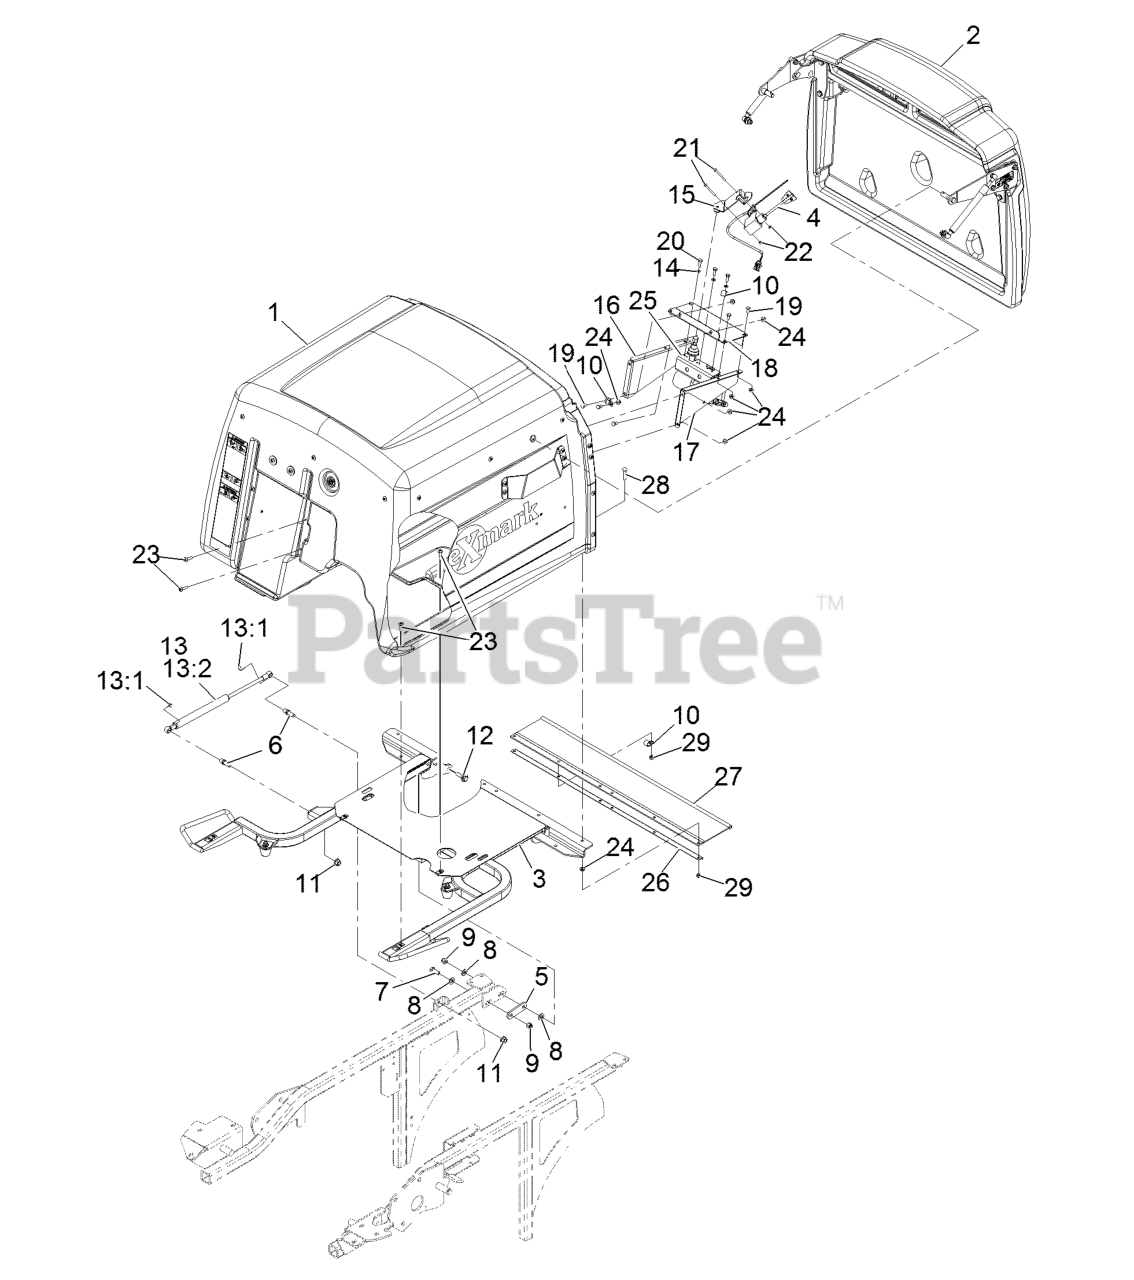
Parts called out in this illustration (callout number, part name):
1	ASM,HOPPER
2	ASM,DOOR HOPPER
3	HOPPER FRAME ASM
4	ASM,FILL SENSOR
5	ARM-LIFT, DECK
6	STUD-BALL
7	SCREW-HH
8	WASHER-FLAT
9	NUT-LOCK, NI
10	CLIP-LOOM
12	SCREW-SHOULDER, HWH
13	DAMPER KIT
13:1	CLIP-RETAINER
13:2	SHOCK-COMPRESSION, GAS
14	WASHER-SPRING
15	MOUNT-SWITCH
16	BRACKET-DRIVE MOTOR, LH
17	BRACKET-DRIVE MOTOR, RH
18	PLATE-SWITCH
19	SCREW-HH
20	SCREW-HH
21	SCREW-PPH
22	NUT-LOCK, NI
23	SCREW-TTH
25	KIT,FILL SENSOR MOTOR
26	CHANNEL-FRAME, HOPPER
27	DEFLECTOR-GRASS
28	SCREW-CARR
29	NUT-LOCK, NI
